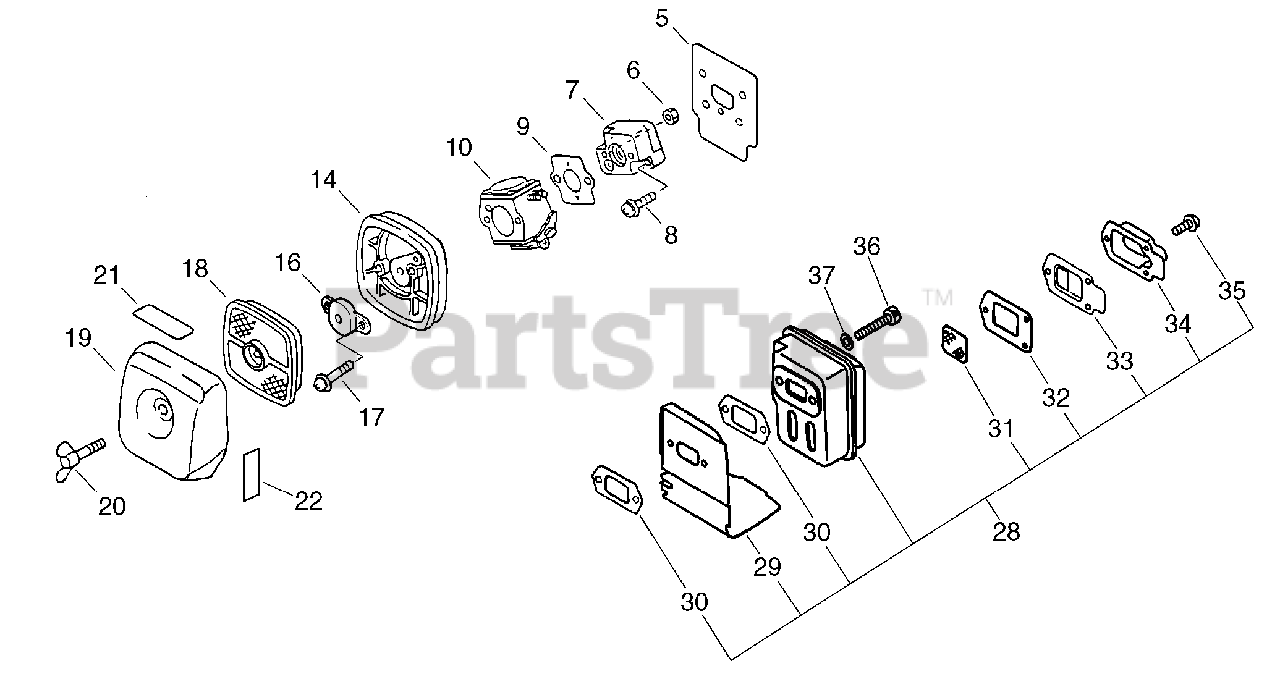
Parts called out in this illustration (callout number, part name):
5	SHIELD, INTAKE
7	INSULATOR, INTAKE
8	SCREW - 5X20
9	GASKET, INTAKE
10	CARBURETOR
14	AIR FILTER CASE ASSY
16	PLATE, PREVENT
17	SCREW - 5X65
18	FILTER, AIR - DOUBLE LAYER
19	COVER, AIR FILTER - BLACK
20	THUMBSCREW
21	LABEL - CHOKE
22	LABEL - CHOKE
28	MUFFLER ASSY
29	SHIELD, EXHAUST
30	GASKET, EXHAUST
31	SCREEN, SPARK ARRESTOR
32	GASKET, EXHAUST
33	GASKET, EXHAUST - INNER
34	GUIDE, EXHAUST - OUTER
35	SCREW - 4X10
36	SCREW - 5X55
37	WASHER - 5
